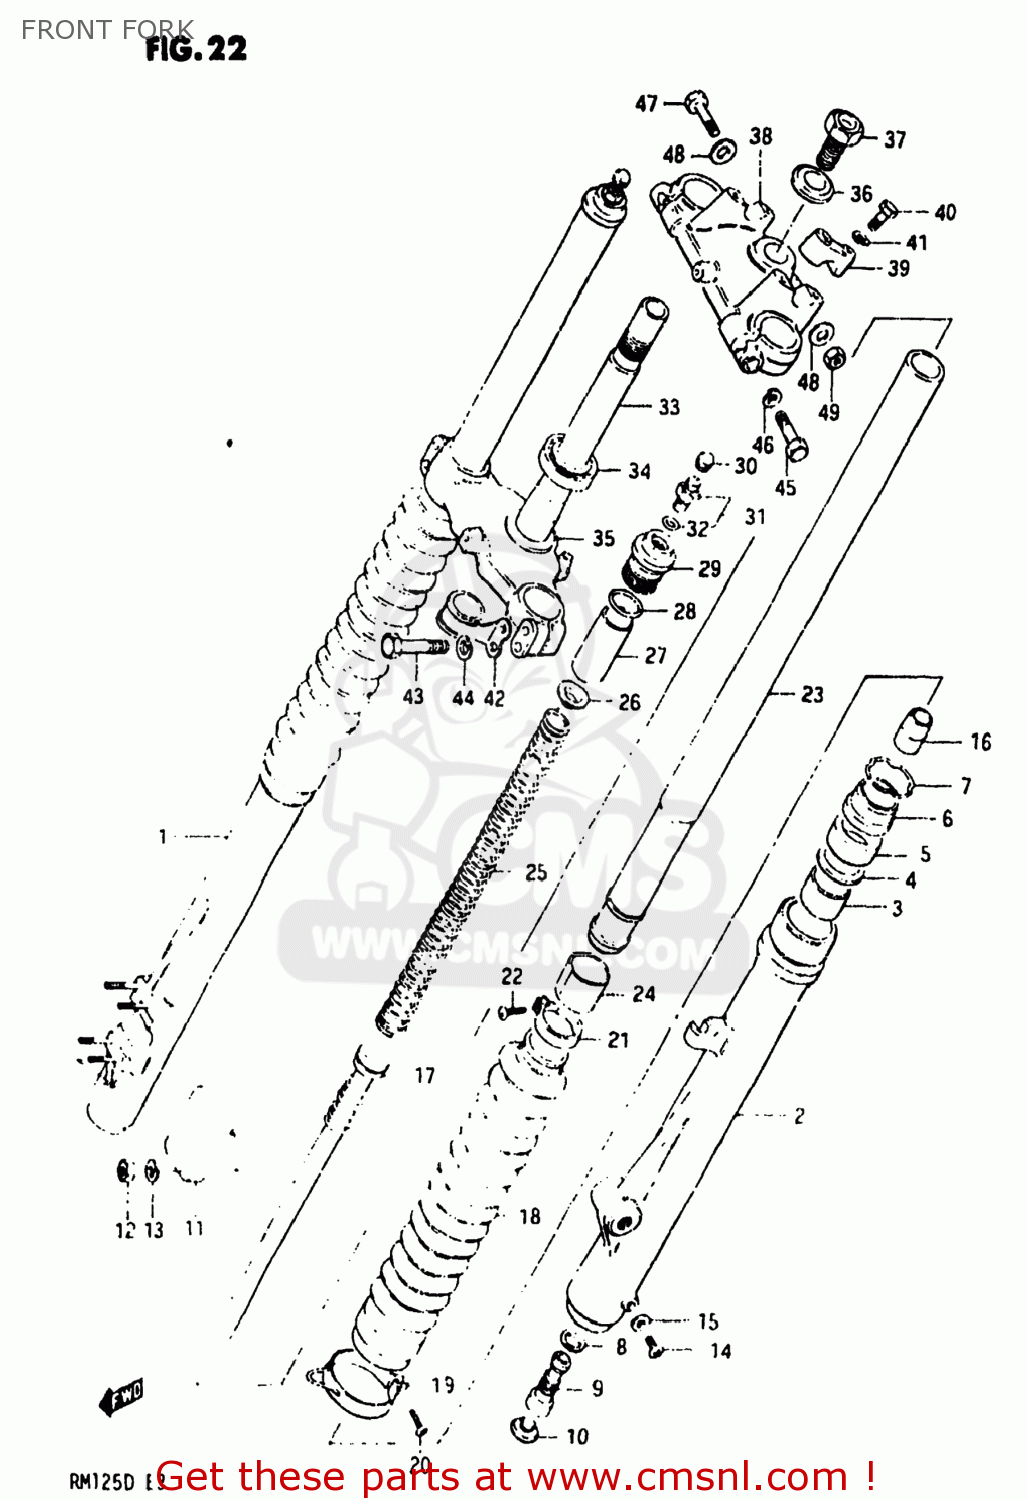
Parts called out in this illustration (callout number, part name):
1	TUBE,OUTER,RIGHT
2	TUBE,FORK,LEFT,OUTER
3	METAL,SLIDE
4	WASHER(40X50X2.3)
5	SEAL,OIL
6	SEAL,DUST
7	RING,STOPPER
8	GASKET,FORK CYLINDER
9	VALVE,DF
10	CAP,FRONT FORK
11	HOLDER,AXLE
12	NUT
13	LOCK WASHER
14	SCREW
15	GASKET,DRAIN,PLUG (NAS)
16	PIECE,OIL LOCK
17	CYLINDER,FRONT FORK
18	BOOT
19	BAND,FRONT FORK BOOT
20	SCREW
21	BAND,BOOT
22	SCREW 4X10
23	TUBE,FORK,INNER
24	PISTON
25	SPRING,FRONT FORK
26	GUIDE
27	SPACER,FRONT FORK SPRING
28	O RING
29	CAP,FORK INNER TUBE
30	CAP,VALVE AIR
31	VALVE,FRONT FORK AIR
32	O-RING
33	STEM,STEERING
34	BEARING
35	WASHER,THRUST
36	WASHER
37	BOLT
38	HEAD,STEERING STEM
39	HOLDER,HANDLE UPR
40	BOLT
41	LOCK WASHER
42	CLIP,CABLE
43	BOLT 8X45
44	LOCK WASHER
45	BOLT
46	LOCK WASHER
47	BOLT 8X50
48	WASHER
49	NUT
